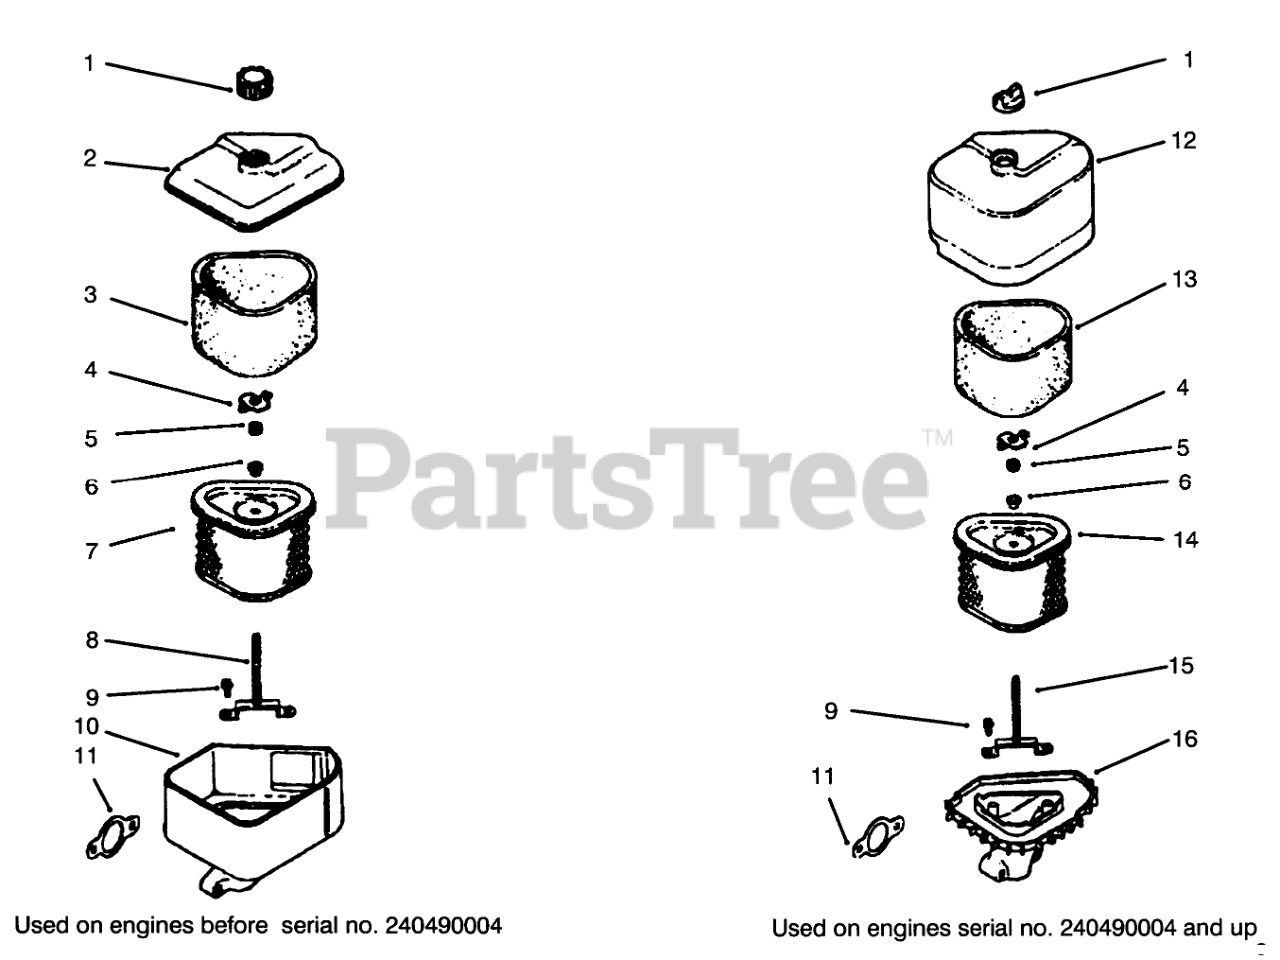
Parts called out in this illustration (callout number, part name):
1	Knob-Cover
2	Cover-Air Cleaner
3	Element-Precleaner
4	Nut-Wing
5	Washer
6	Grommet
7	Element-Air Cleaner
8	Plate-Stud
9	Screw
10	Base
11	Gasket
12	Cover-Air Cleaner
13	Precleaner-Element
14	Element-Air Cleaner
15	Stud-Mounting Plate
16	Base-Air Cleaner
